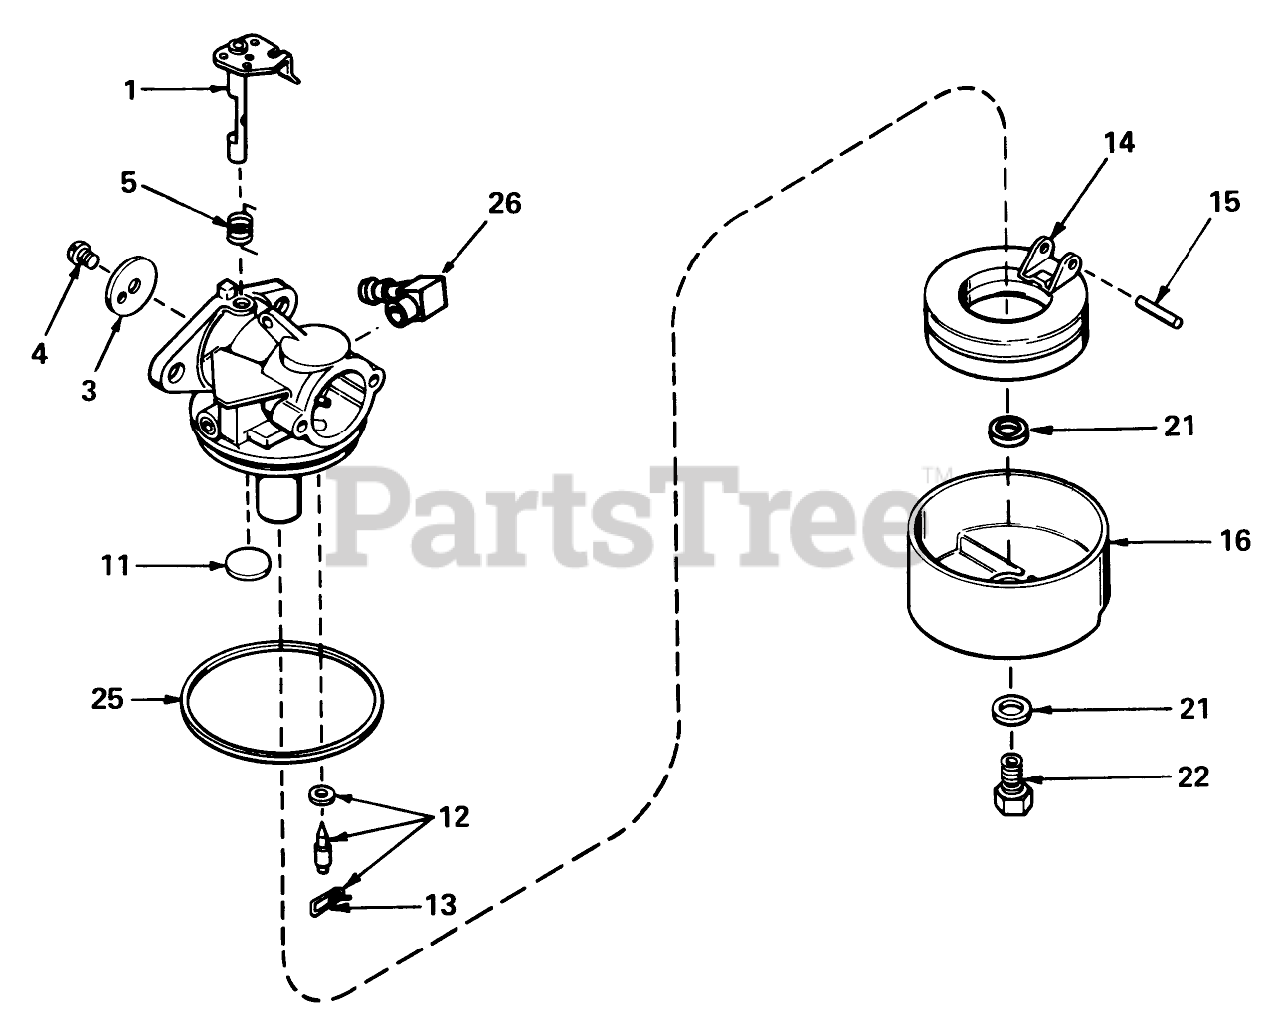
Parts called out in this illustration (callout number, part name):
1	Throttle Shaft and Lever ASM
3	Throttle-Shutter
4	Screw-Shutter
5	Spring, Return
11	Plug-Welch, Atmospheric Vent
12	Inlet Needle, Seat Clip Assy. (Incl. No. 13)
13	Clip-Spring
14	Float,Carburetor
15	Shaft-Float
16	Bowl Float
21	Gasket-Bowl
22	Nut, Float Bowl
25	O Ring-Bowl, Float
26	Fitting, Fuel Inlet
